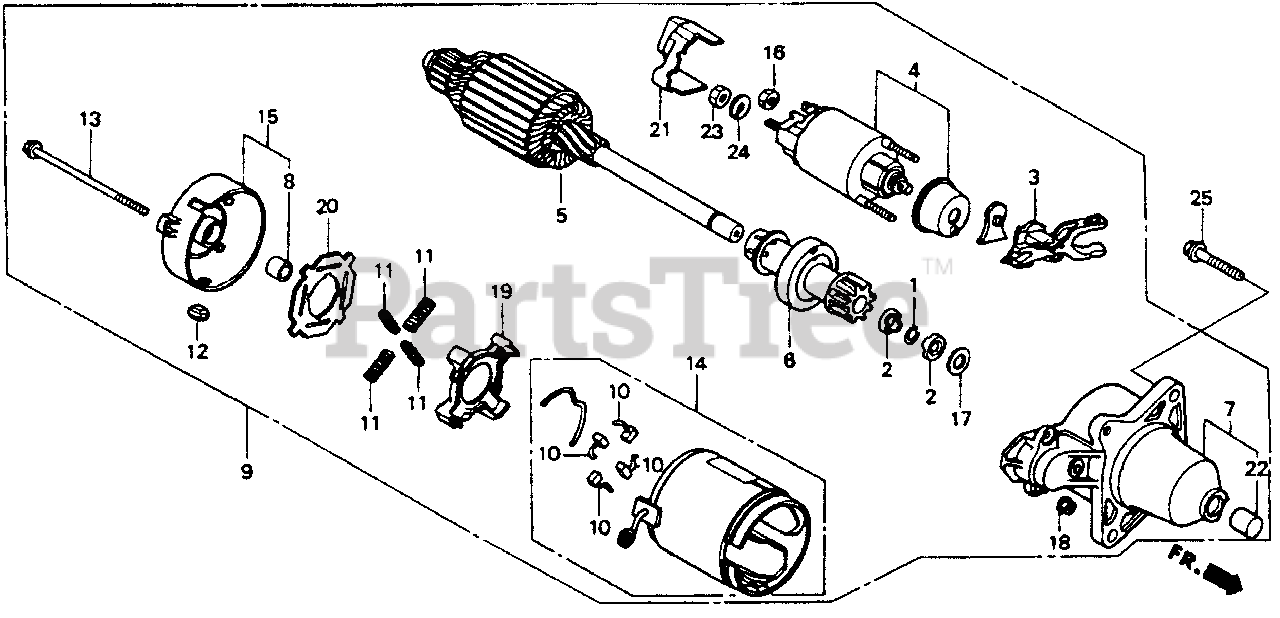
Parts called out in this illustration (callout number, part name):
1	RING, SNAP (DENSO)
2	COLLAR, CLUTCH STOP
3	LEVER, PINION DRIVE
4	SWITCH ASSY., MAGNETIC
5	ARMATURE
6	CLUTCH, OVERRUNNING
7	HOUSING, DRIVE SIDE
8	BEARING B
9	MOTOR ASSY., STARTER
10	BRUSH
11	SPRING, BRUSH
12	COVER
13	BOLT, THROUGH
14	YOKE
15	FRAME, COMMUTATOR END
16	NUT, HEX. (8MM)
17	WASHER
18	NUT, FLANGE (5MM)
19	HOLDER, BRUSH
20	INSULATOR, BRUSH HOLDER
21	COVER, TERMINAL
22	BEARING A
23	NUT, HEX. (8MM)
24	WASHER, SPRING (8MM)
25	BOLT, FLANGE (8X28)
